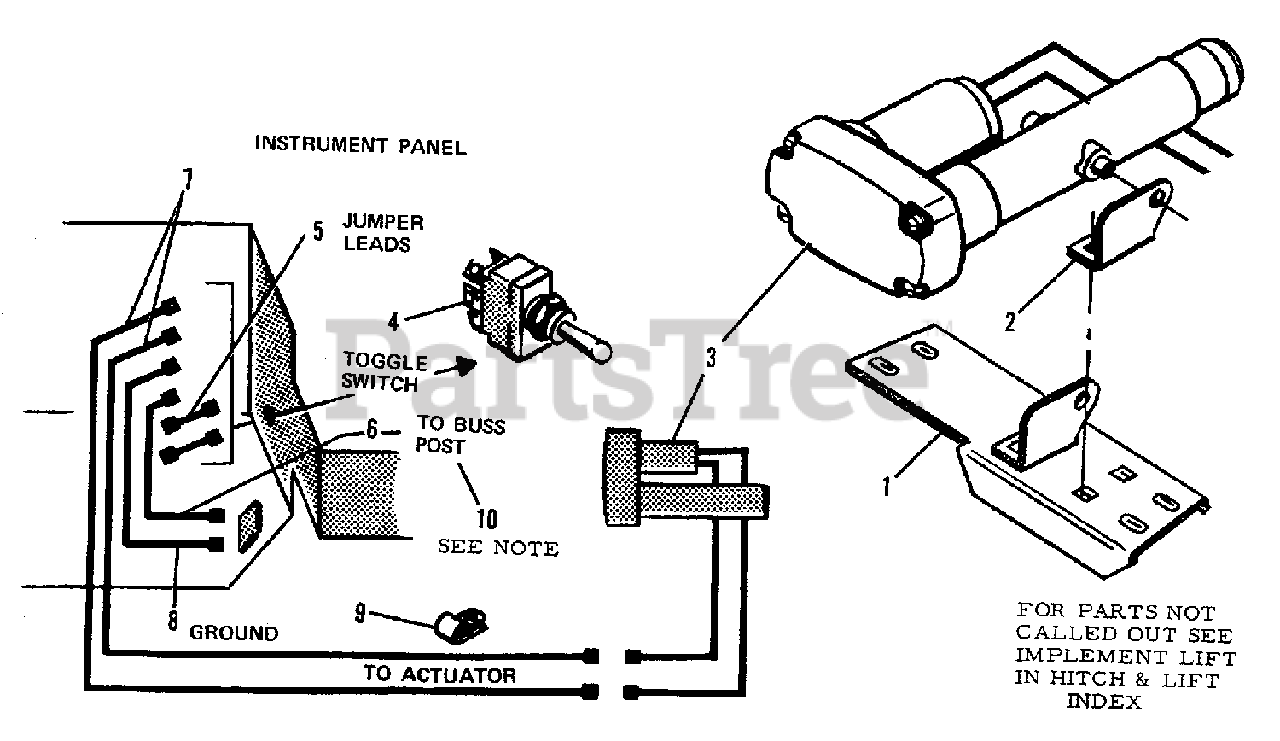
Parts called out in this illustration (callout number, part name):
1	SUPPORT, Actuator
2	BRACKET, Actuator Support
3	ACTUATOR, Electric
4	SWITCH, Toggle (Screw Type Terminals)
4	SWITCH, Toggle (Slide Type Terminals)
5	LEAD, Jumper (For Screw Type Terminal Only)
6	*LEAD, Buss Post To Switch (For Screw Type Terminal Only)
7	HARNESS ASSEMBLY, Switch To Actuator (For Screw Type Terminal)
7	HARNESS ASSEMBLY, Switch To Actuator (For Slide Type Terminal)
8	*LEAD, Switch to Ground (For Screw Type Terminal)
8	*LEAD, Switch To Ground (For Slide Type Terminal - Also Replaces 1 Jumper Lead)
9	CLIP, #6 Open
10	*LEAD, Lift Switch to PTO Switch (For Slide Type Terminal - Aslo Replaces 1 Jumper Lead)
